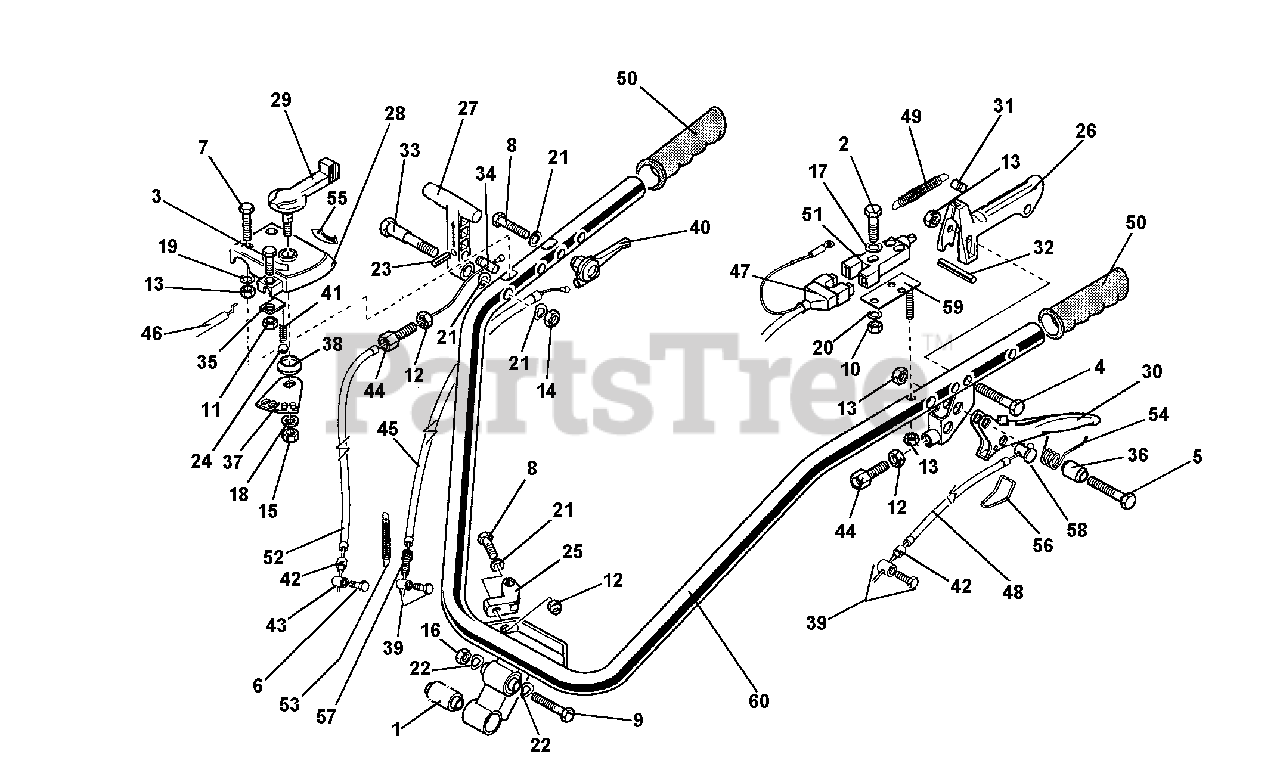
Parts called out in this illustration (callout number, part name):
1	SILENTBLOCK
2	SCREW TE M4X25
3	SCREW, M5X10
4	SCREW, TE M6X45
5	SCREW, M6X25
6	SCREW, TE M6X16
7	SCREW, M6X40
8	SCREW, M8X35
9	SCREW, M10X80
13	NUT, SELF LOCKING M6
17	FLAT WASHER, M4.3
18	WASHER, M8.4
19	LOCK WASHER, M6.4
20	LOCK WASHER, M4.3
21	LOCK WASHER, M8.4
22	WAVE WASHER, M10.4
23	PIN, LOCKING, M4X20
25	SUPPORT, CONTROL ROD
26	MOTOR STOP LEVER
27	REVERSER LEVER
29	THROTTLE LEVER
30	CLUTCH LEVER
32	LEVER STOP FOR MOTOR STOP
34	DRILLED PIN
36	LEVER SPACER
37	THROTTLE LEVER
39	CLAMP, CABLE
40	LEVER, ACCELERATOR
43	PIN, CABLE CLAMP
44	SCREW, ADJUSTING, M8
45	THROTTLE CABLE
46	THROTTLE CABLE, B&S
47	SWITCH WIRING HARNESS
48	CLUTCH CABLE
51	STOP SWITCH
52	REVERSER CABLE
53	SPRING, KOHLER ENGINE
54	LEVER SPRING
55	THROTTLE DECAL
57	CABLE ADJUSTER
59	SWITCH PLATE
